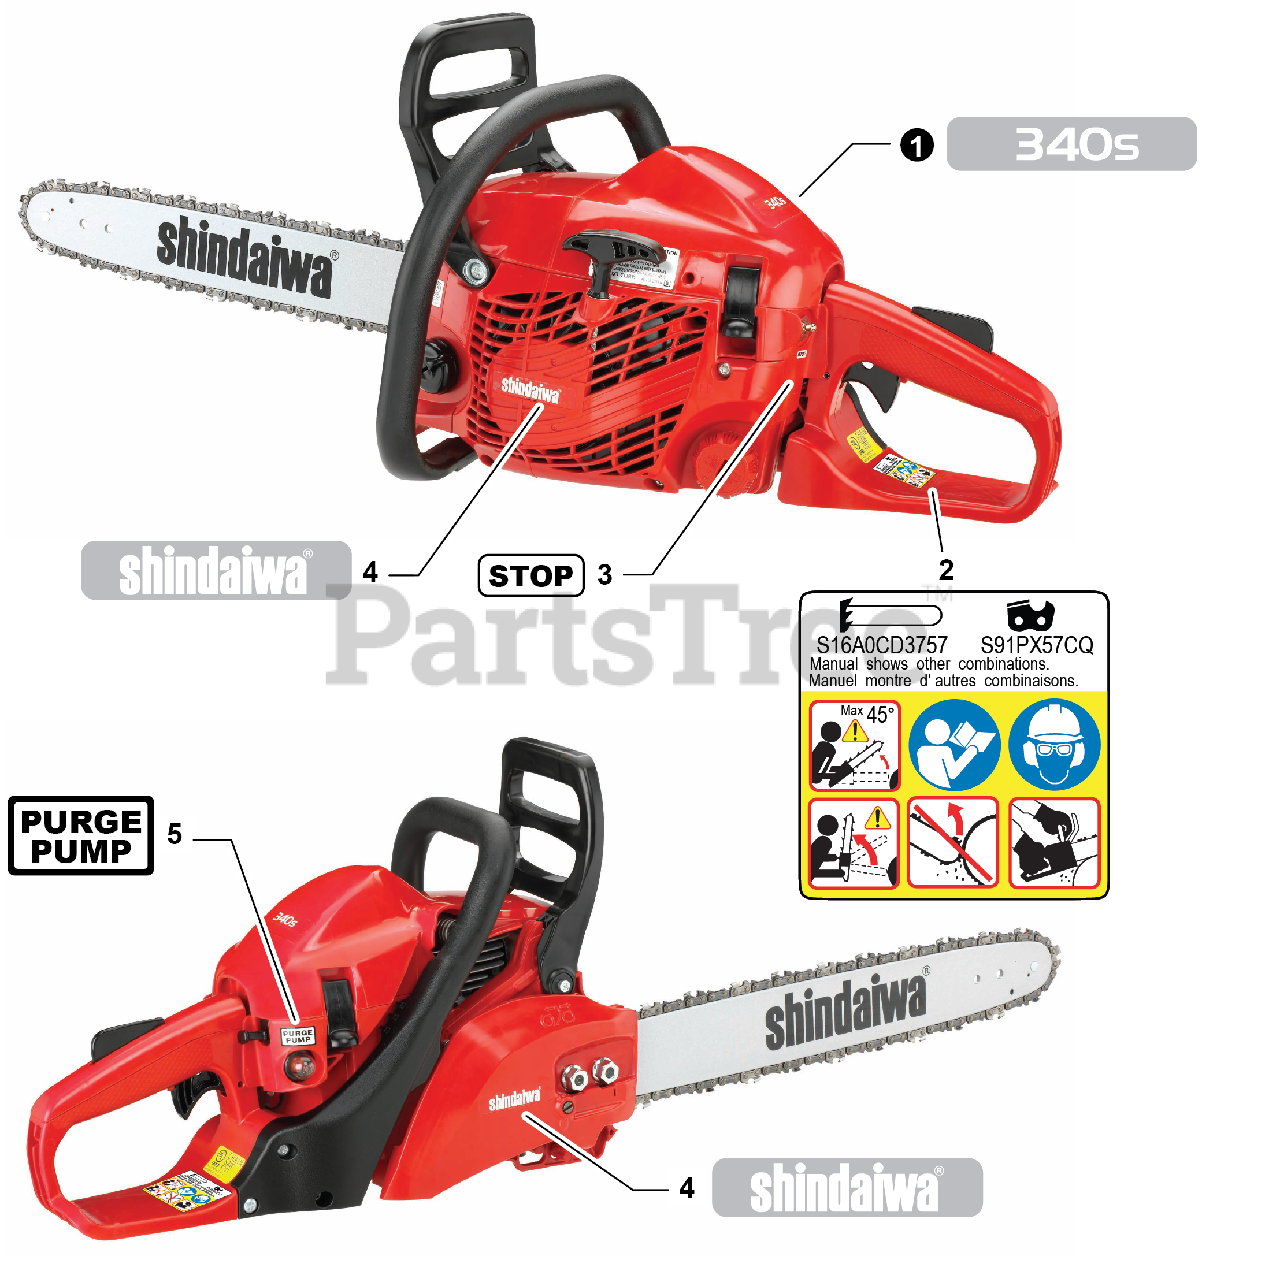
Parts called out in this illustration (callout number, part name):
1	LABEL - MODEL 340S
2	LABEL, CAUTION
3	LABEL, STOP
4	LABEL - SHINDAIWA
5	LABEL, PURGE PUMP
